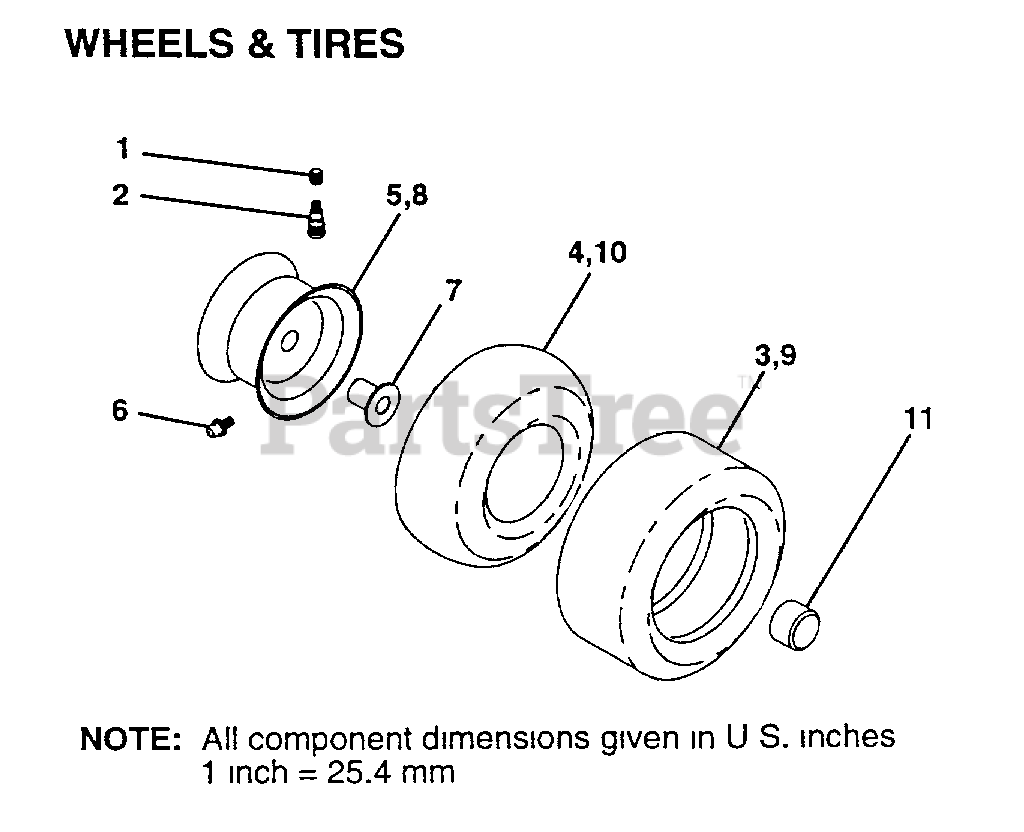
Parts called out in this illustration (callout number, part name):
1	VALVE CAP
2	VALVE STEM LT
4	TUBE.5.3/4.5/6
5	"RIM,FRT T"
6	FITTING LT
7	"FLANGE, BEARING"
8	RIM.REAR.417
10	TUBE.23X8/10-12
11	HUB CAP
